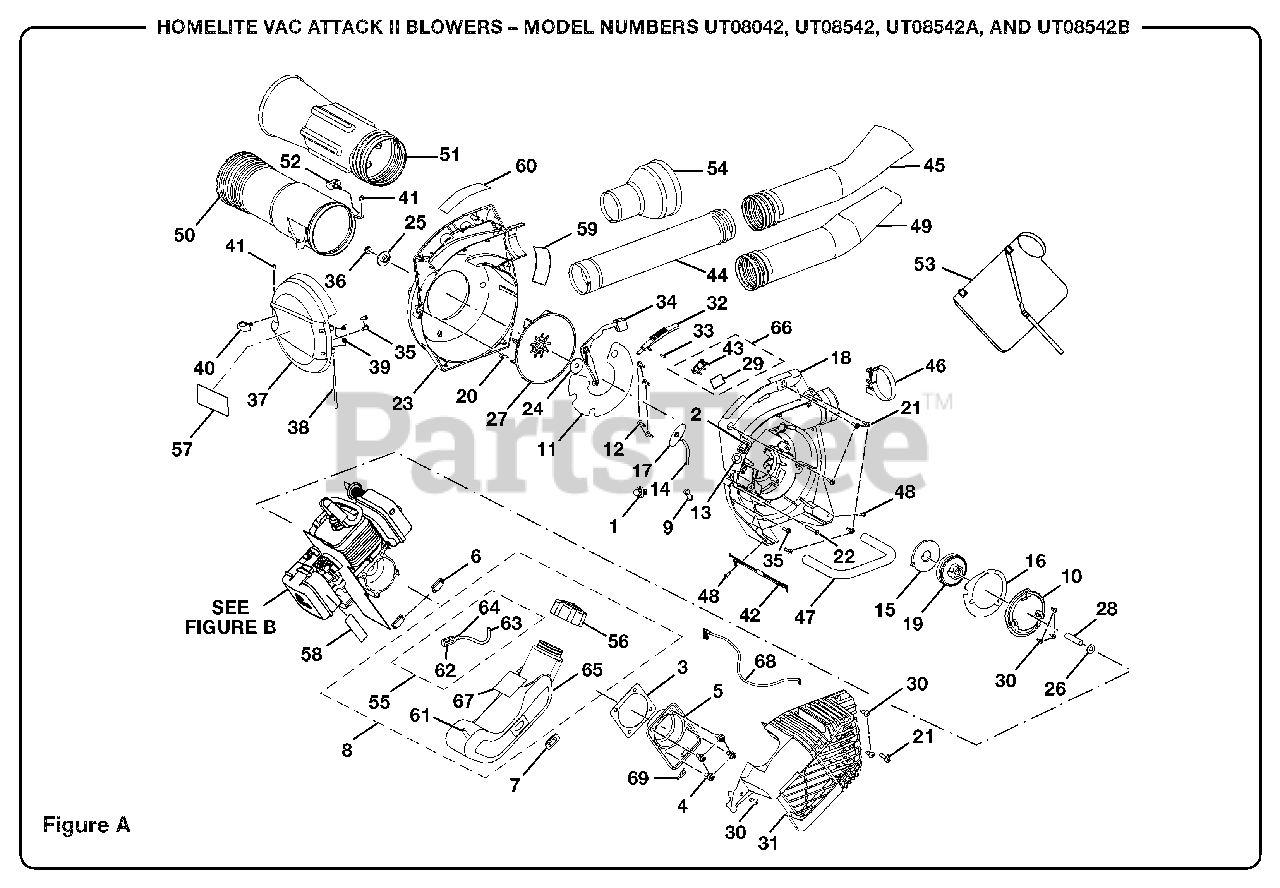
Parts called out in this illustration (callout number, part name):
1	PRIMER BULB
2	SWITCH
3	CRANKCASE GASKET
4	SCREW (10-24 x 9/16 in. PAN HD.)
5	CRANKCASE COVER
6	RUBBER BUMPER
7	BIG BUMPER
8	FUEL TANK ASSEMBLY
9	BUSHING-STARTER ROPE
10	BAFFLE PLATE
11	INNER VOLUTE SEAL
12	SCREW (10-24 x 3/4 in. TRUSS HD.)
13	BUSHING STARTER
14	STARTER ROPE
15	SPRING & CONTAINER
16	BAFFLE GASKET
17	STARTER GRIP
18	INNER VOLUTE HOUSING
19	PULLEY ASSEMBLY
20	WIRE LOOP
21	SCREW (10-14 x 3/4 in. TORX TRUSS HD.)
22	SCREW (10 x 1-5/8 in. HEX HD.)
23	OUTER VOLUTE
24	FLAT WASHER
25	FAN ADAPTOR
26	FLAT WASHER
27	FAN
28	FAN SPACER
30	SCREW (#8 x 1/2 in. PAN HD.)
31	BLOWER SHROUD
33	SLIDE PIN
35	SCREW (10-24 x 3/4 in. TORX TRUSS HD.)
36	LOCK NUT (3/8-24)
38	DOOR HINGE SHAFT
39	DOOR HINGE SPRING
40	BLOWER KNOB
42	WIRING HARNESS
43	SCREEN COVER
44	UPPER TUBE
45	LOWER NOZZLE
47	LOWER HANDLE
48	SCREW
49	SWEEPER NOZZLE
50	UPPER VACUUM TUBE
51	LOWER VACUUM TUBE
52	BLOWER KNOB
54	VACUUM BAG TUBE
55	FUEL FILTER KIT
56	FUEL CAP ASSEMBLY
57	DOOR LABEL
58	CHOKE LABEL
59	FAN INTAKE WARNING LABEL
60	WARNING/STARTING LABEL
61	RUBBER TUBING (196.85 mm)
62	FUEL FILTER
63	RUBBER TUBING (114.3 mm)
64	WIRE CLAMP
65	FUEL TANK
66	SCREEN COVER & NETTING ASSEMBLY
67	HEAT SHIELD
68	LEAD W/TERMINALS
